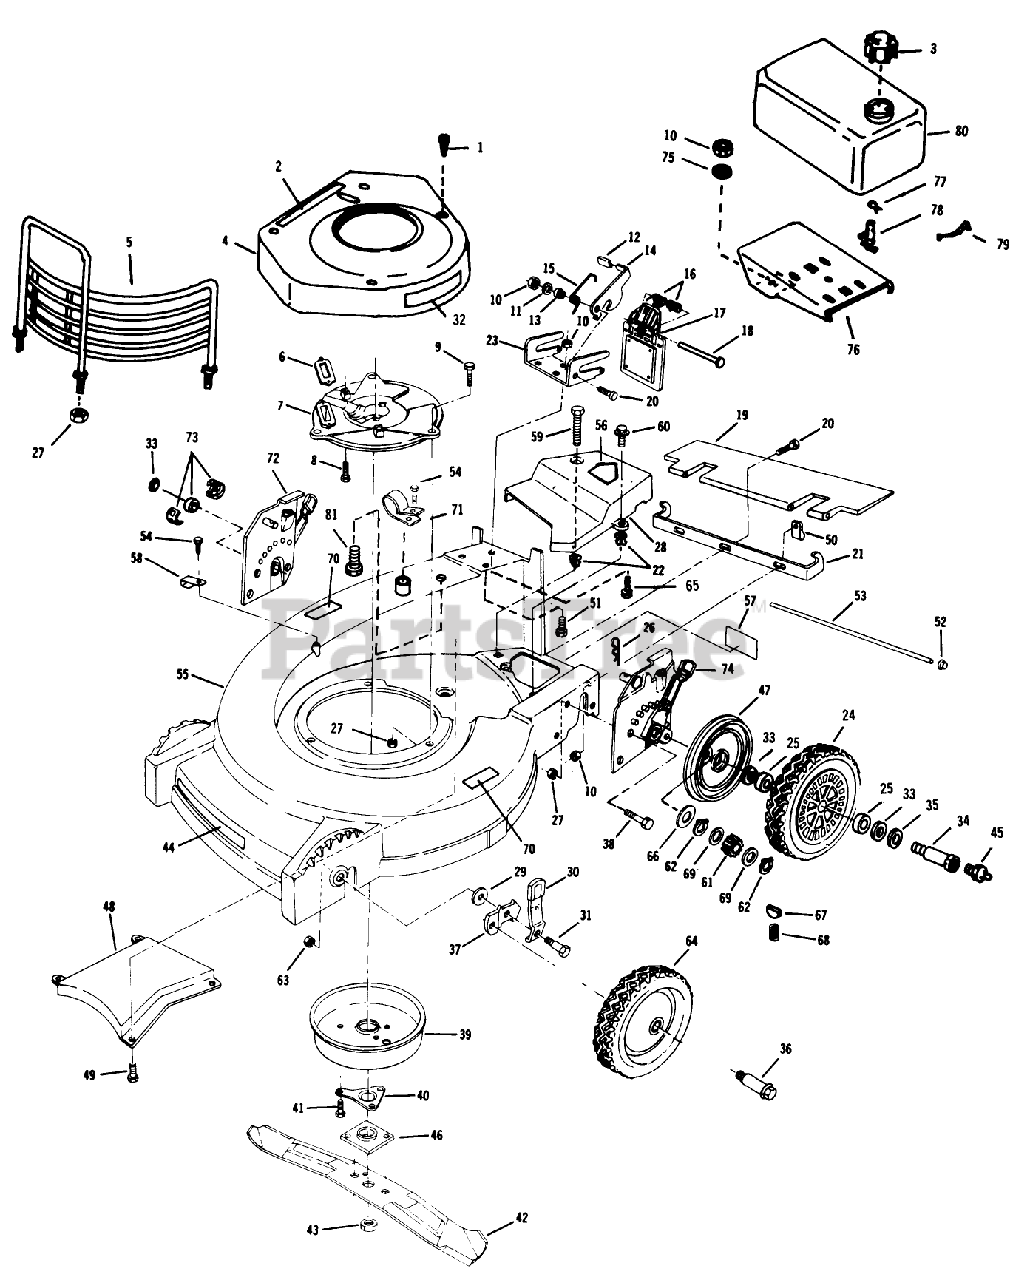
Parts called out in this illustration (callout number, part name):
1	SCREW - SELF TAPPING
3	FUEL CAP & INSERT
4	SHROUD S
7	PLATE F
8	SCREW V
9	SCREW-HH
10	LOCKNUT E
15	SPRING
16	SPRING ASOC
18	ROD (RB&W)
19	T/SHIELD SM&P
26	HAIR PIN
27	NUT-LOCK F
29	WASHER
31	BOLT
33	WASHER
35	SPACER
36	BOLT-SHOULDER
39	MUFFLER COVER F
40	SUPPORT F
41	SCREW
43	NUT-BLADE
45	FITTING LINCOLN
46	PLATE AND COLLAR ASM
48	BAFFLE CHUTE PL
51	SCREW
54	SCREW LAWRENCE
60	SCREW
61	PINION BROCKWAY
62	RET RING
63	LOCKNUT
64	WHEEL/TIRE ASM
65	SCREW HEX WASHER
66	THRUST WASHER
67	KEY
68	SPRING
69	SPACER/GR ALGHNY
73	REAR AXLE BEARING
74	HEIGHT ADJUSTER AY
75	WASHER
77	CLAMP - HOSE S
78	VALVE&SCREEN SM
79	SPRING
